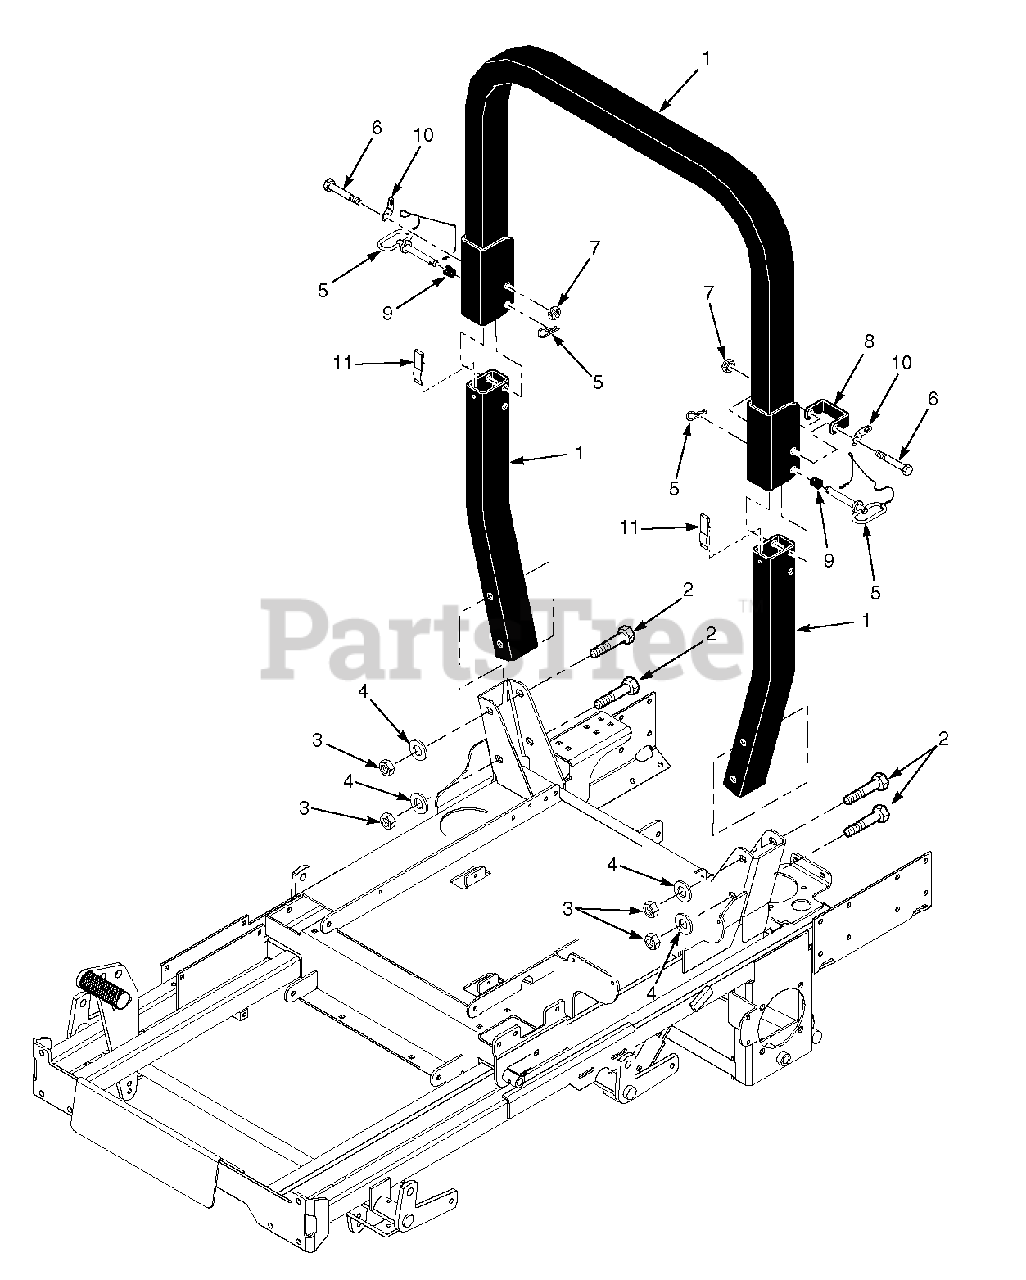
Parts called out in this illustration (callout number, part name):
1	STT, ROPS
2	Bolt, Hex Head 1/2-13 x 4"
3	Nut, Center Lock 1/2-13
4	Flatwasher, 1/2-.562 x 1.375 x .109
5	Pin Assembly
6	Bolt, Hex Head 1/2-13 x 3-3/4"
7	Nut, Center Lock 1/2-13
8	Stop Bracket, ROPS
9	Spring, ROPS
10	Clip, ROPS
11	Spring Clip, ROPS
